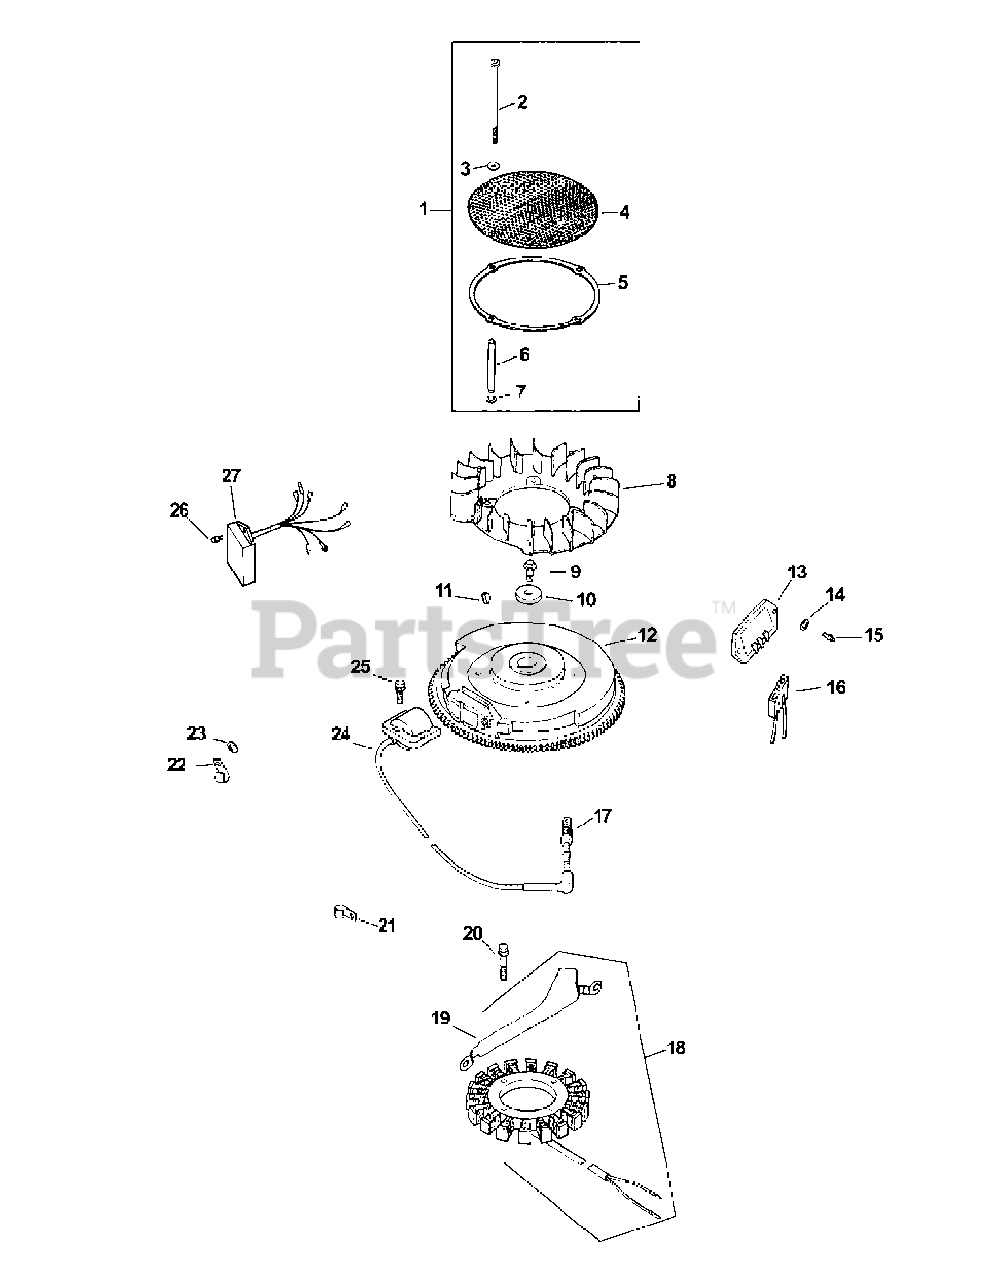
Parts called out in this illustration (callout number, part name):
1	Chopper Screen Kit
2	Hex Head Screw (M6 x 1.0 x 100)
3	Plain Washer (5/16")
5	Support Ring
6	Grass Screen Spacer
7	Spring Washer
8	Fan
9	Hex Flange Screw (M10 x 1.5 x 46)
10	Plain Washer (3/8")
13	Regulator - Rectifier
14	Plain Washer (3/16")
15	Phillips Head Screw (11-16 x 7/8")
16	Connector (3 Contact)
17	Spark Plug
18	15 amp Stator Kit
19	Stator Wire Bracket
20	Hex Cap Screw (M5 x .8 x 25)
23	Plain Washer (1/4")
24	Ignition Module
25	Hex Flange Screw (M5 x .8 x 20)
26	Screw (M4 x .7 x 10)
27	Speed Advance Module
